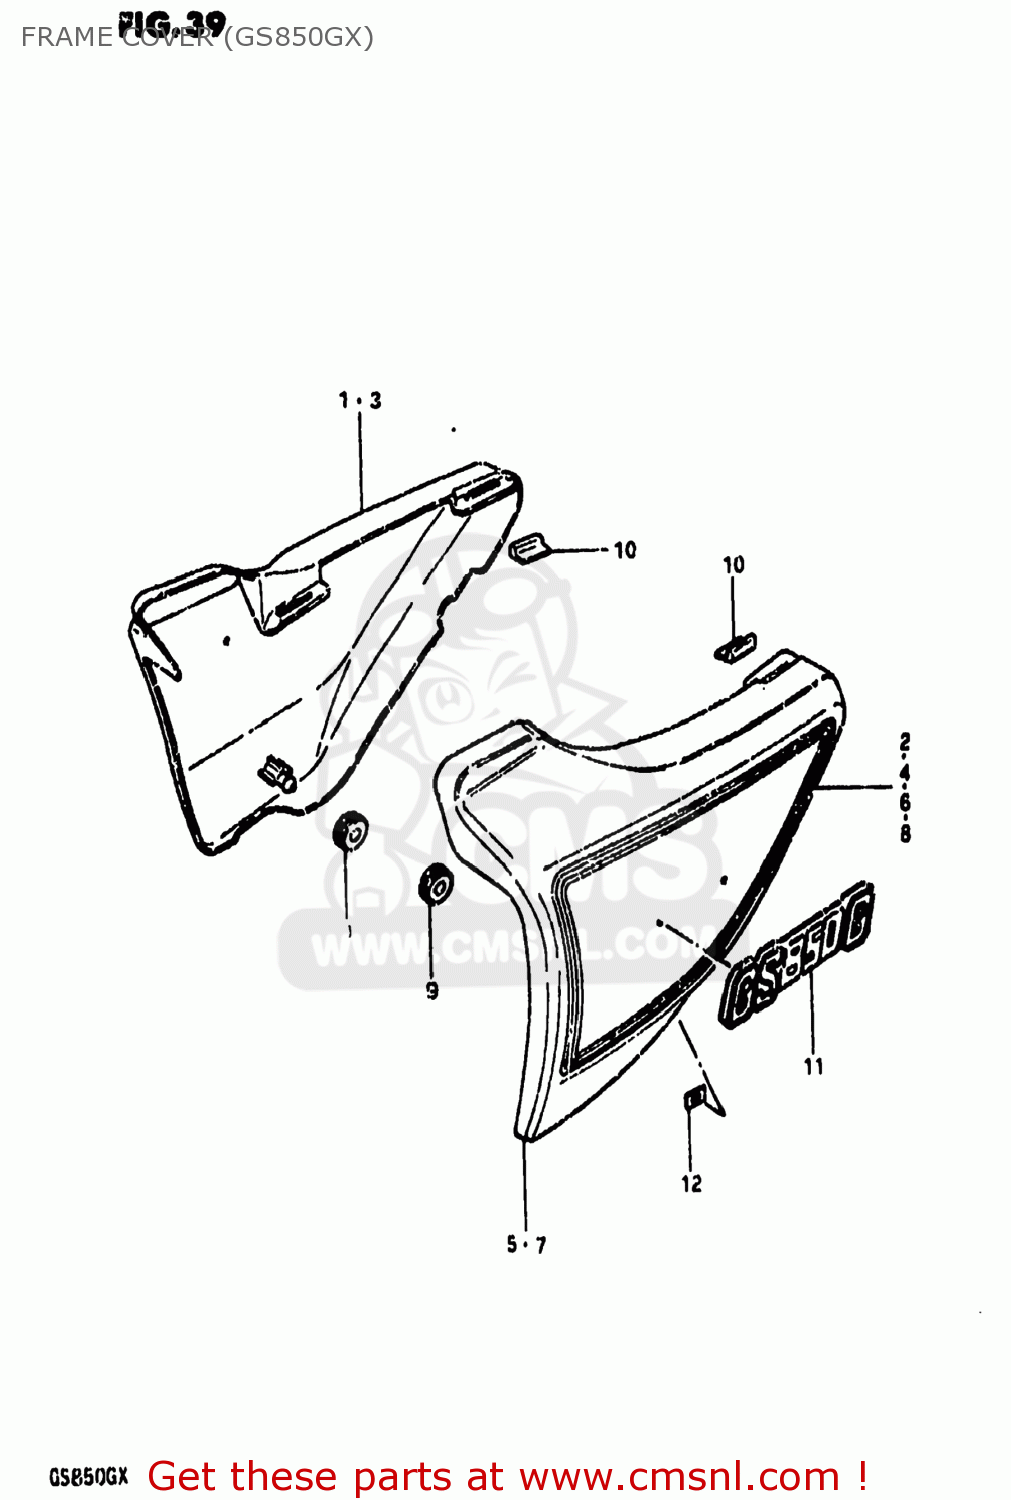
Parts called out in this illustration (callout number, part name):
1	COVER ASSEMBLY,FRAME,RIGHT
2	TAPE SET,FRAME COVER
3	COVER ASSEMBLY,FRAME,RIGHT
4	TAPE SET,FRAME COVER
5	COVER ASSEMBLY,FRAME,LEFT
6	TAPE SET,FRAME COVER
7	COVER ASSEMBLY,FRAME,LEFT
8	TAPE SET,FRAME COVER
9	CUSHION
10	CUSHION,FRAME COVER
11	EMBLEM,FRAME COVER
12	NUT
